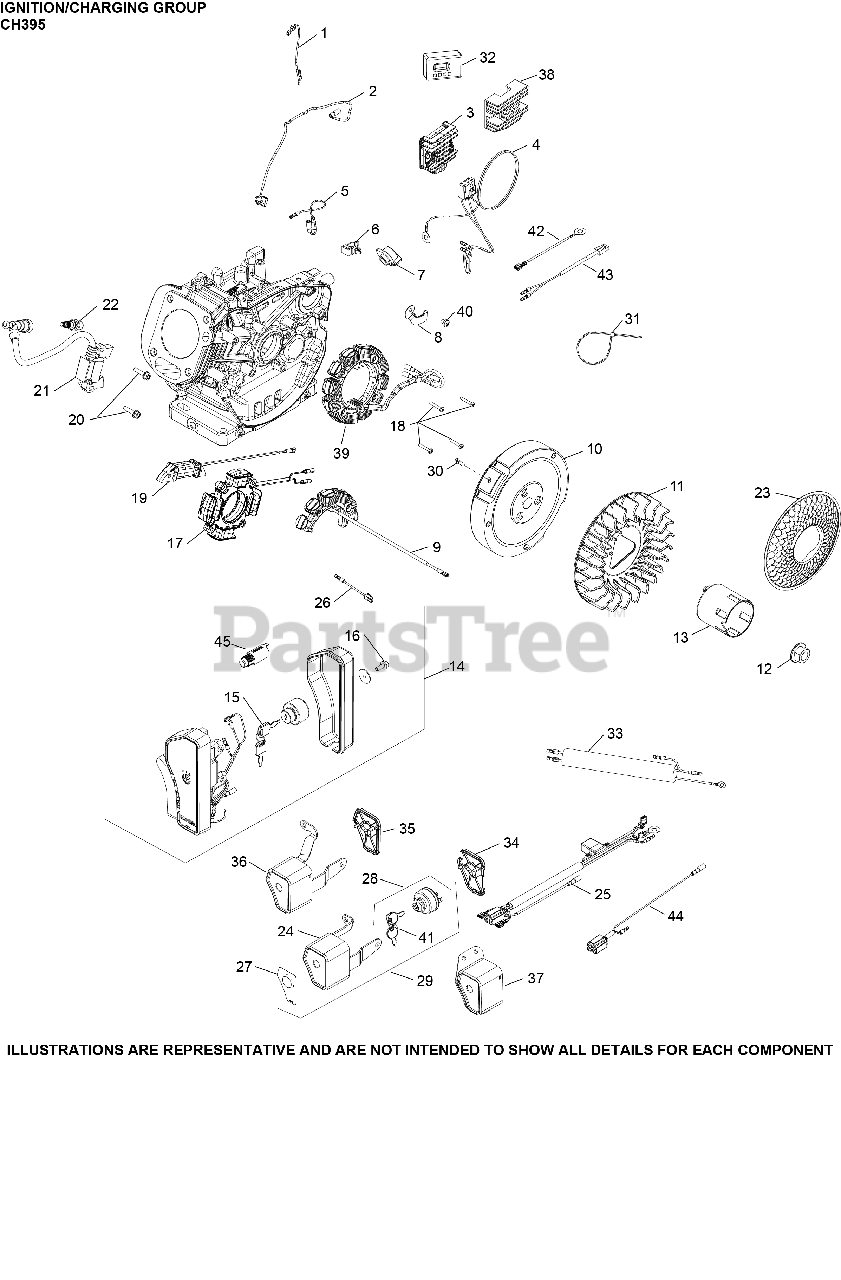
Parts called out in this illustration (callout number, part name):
2	LEAD, GROUND TO KILL
6	CLIP, WIRE HARNESS
7	SWITCH, IGNITION
10	FLYWHEEL ASSY,CAST IRON (RECOIL)
11	FAN, FLYWHEEL
12	NUT, FLYWHEEL
13	CUP, STARTER DRIVE
20	SCREW, M6 X 25 USE 25 086 436-S
21	MODULE, SPARK PLUG ASSY
22	SPARK PLUG
